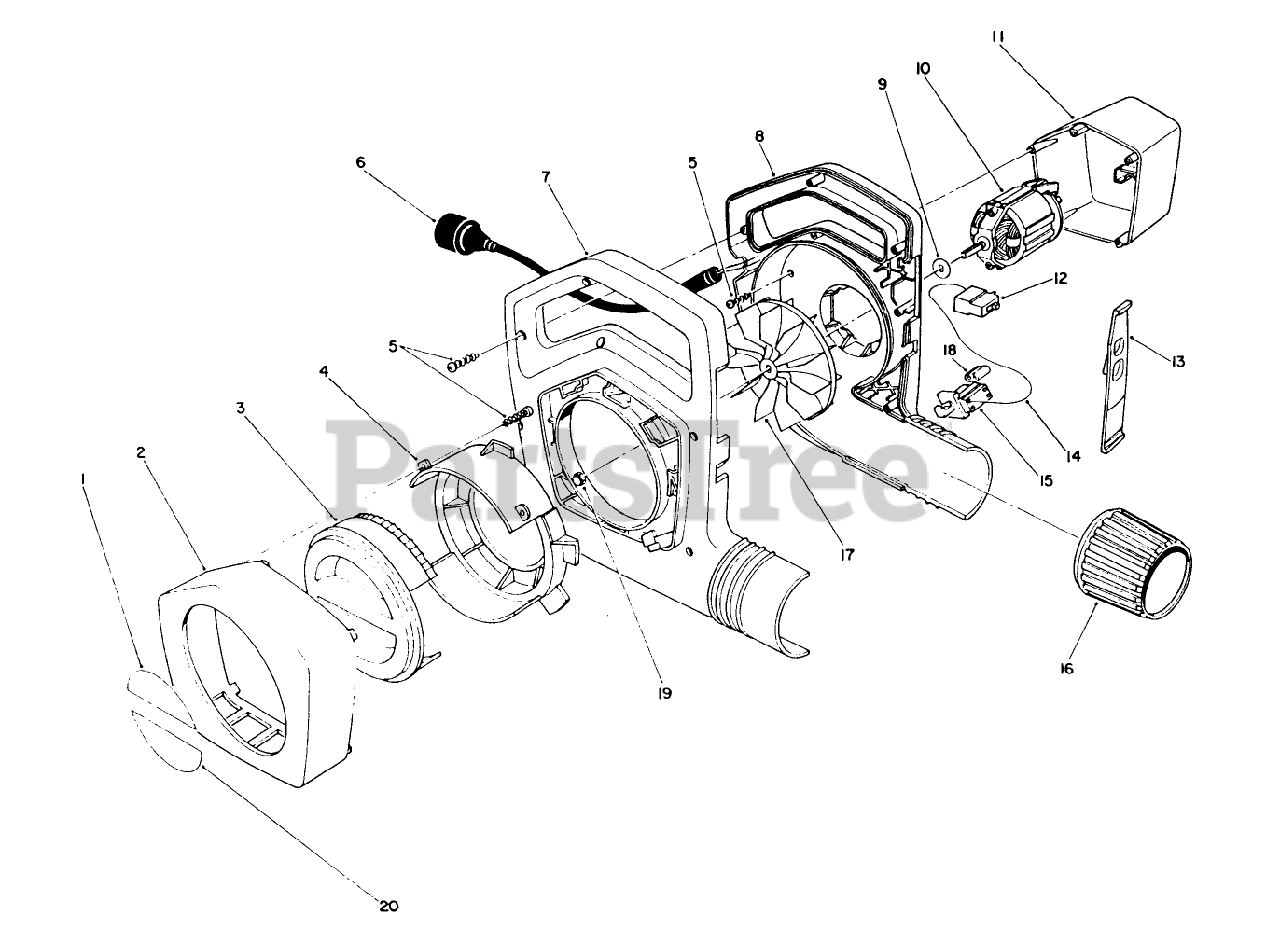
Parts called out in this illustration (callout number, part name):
10	MOTOR, BLOWER (450/550)
15	SWITCH-INTERLOCK
19	NUT-ACORN
